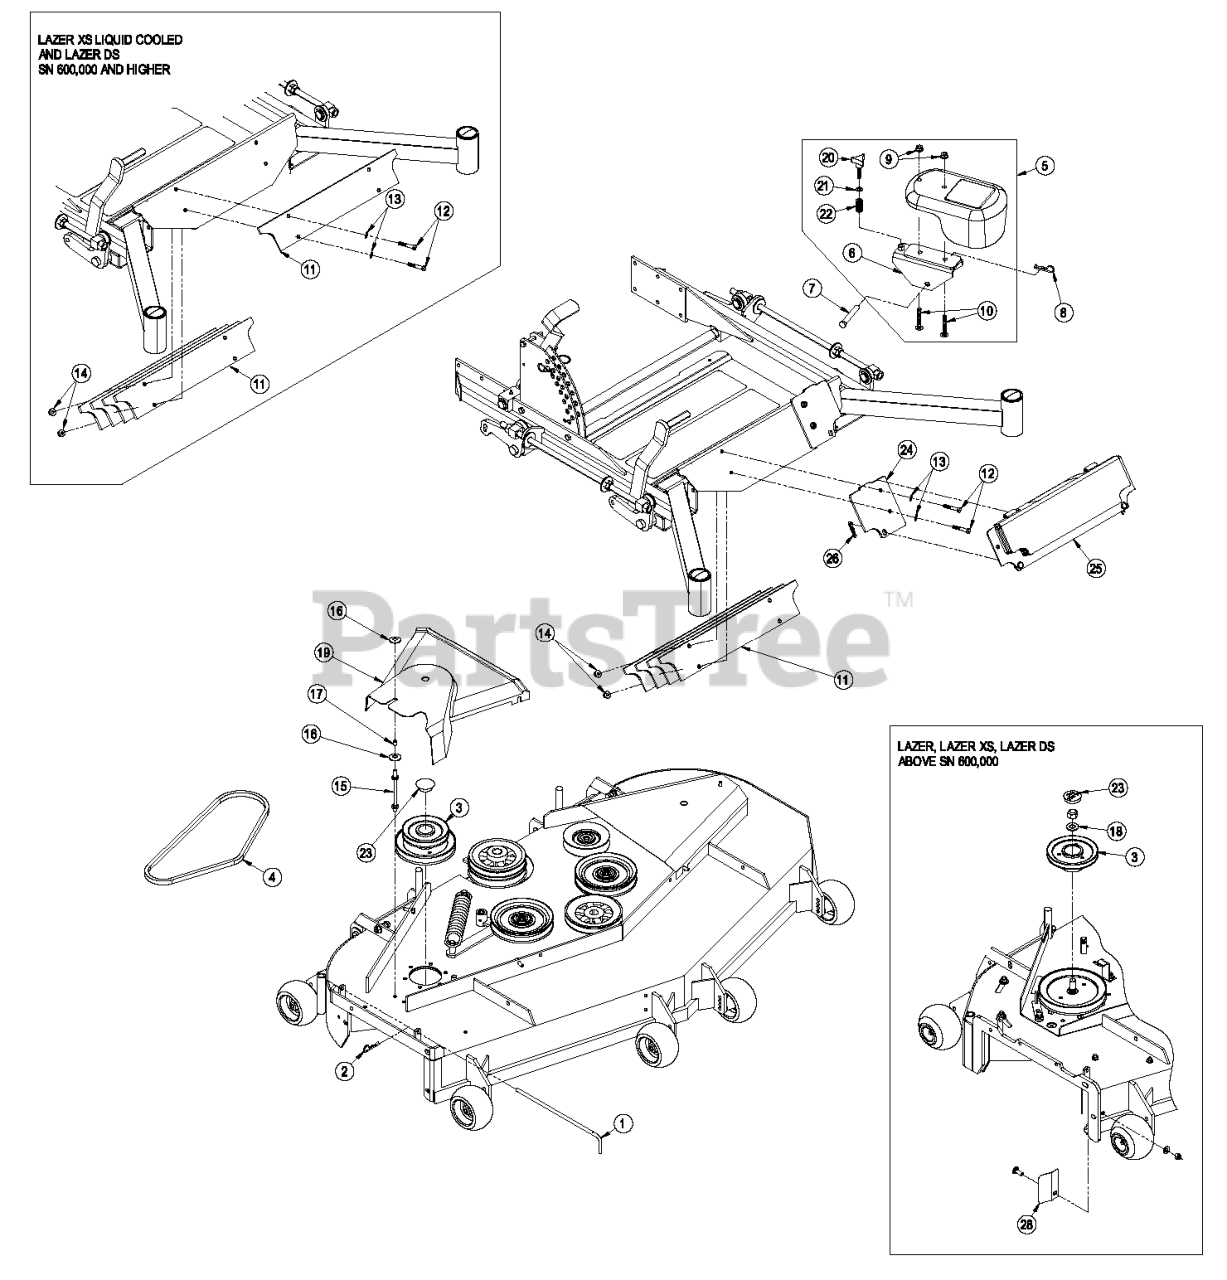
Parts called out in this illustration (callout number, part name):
1	PIN,CHUTE PIVOT
2	PIN-COTTER
3	JACKSHAFT, LZUV72
4	BELT, BLOWER DRIVE 72
5	ASM, WEIGHT 2.0" 43 POUND
6	WLD, BRACKET 2.0 ARM
7	PIN-CLEVIS
8	PIN-COTTER
9	NUT-HHF, WHIZ
10	BOLT-SQH
11	PLATE, WEIGHT
12	SCREW-HH
13	WASHER-PLAIN
15	STUD,BELT SHIELD 4 INCH
17	Spacer, Grommet
18	Washer, 5/8 SAE
19	COVER, BELT 72
21	WASHER-FLAT
23	PLUG, BLACK NYLON 1.75
24	PLATE, WEIGHT MOUNTING
25	ASM, WEIGHT PLATE WITH DE
26	PIN-HAIR
28	Deflector
